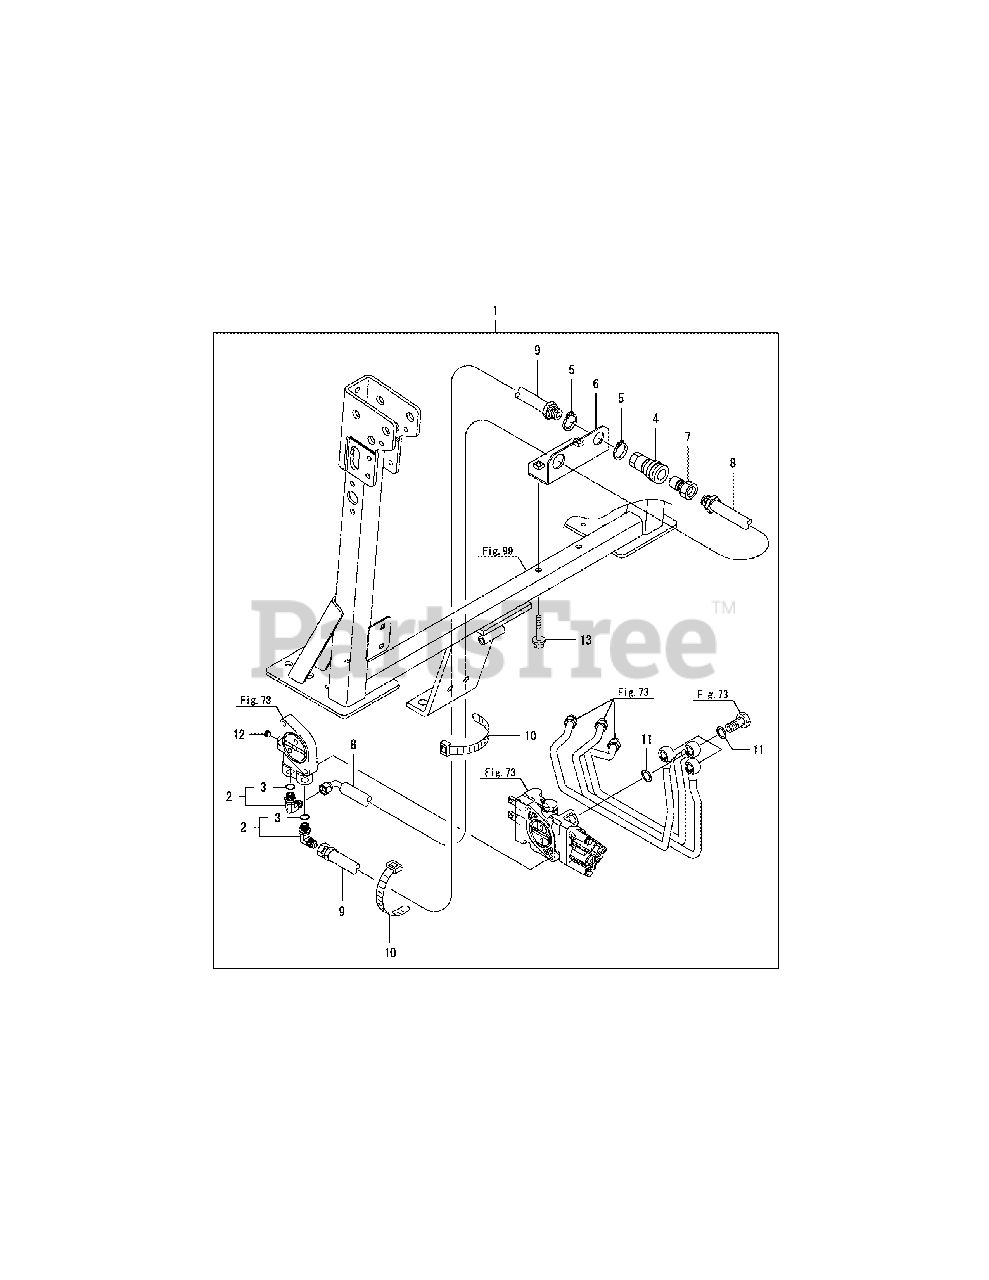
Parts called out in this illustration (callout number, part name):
1	POWER BEYOND KIT
2	JOINT,90SAE9/16-18
3	PACKING, JOINT
4	COUPLER,QUICK 3/8F
7	COUPLER,QUICK 3/8M
12	PLUG PT1/8,SCREW
13	BOLT M 8X 50 PLATED
